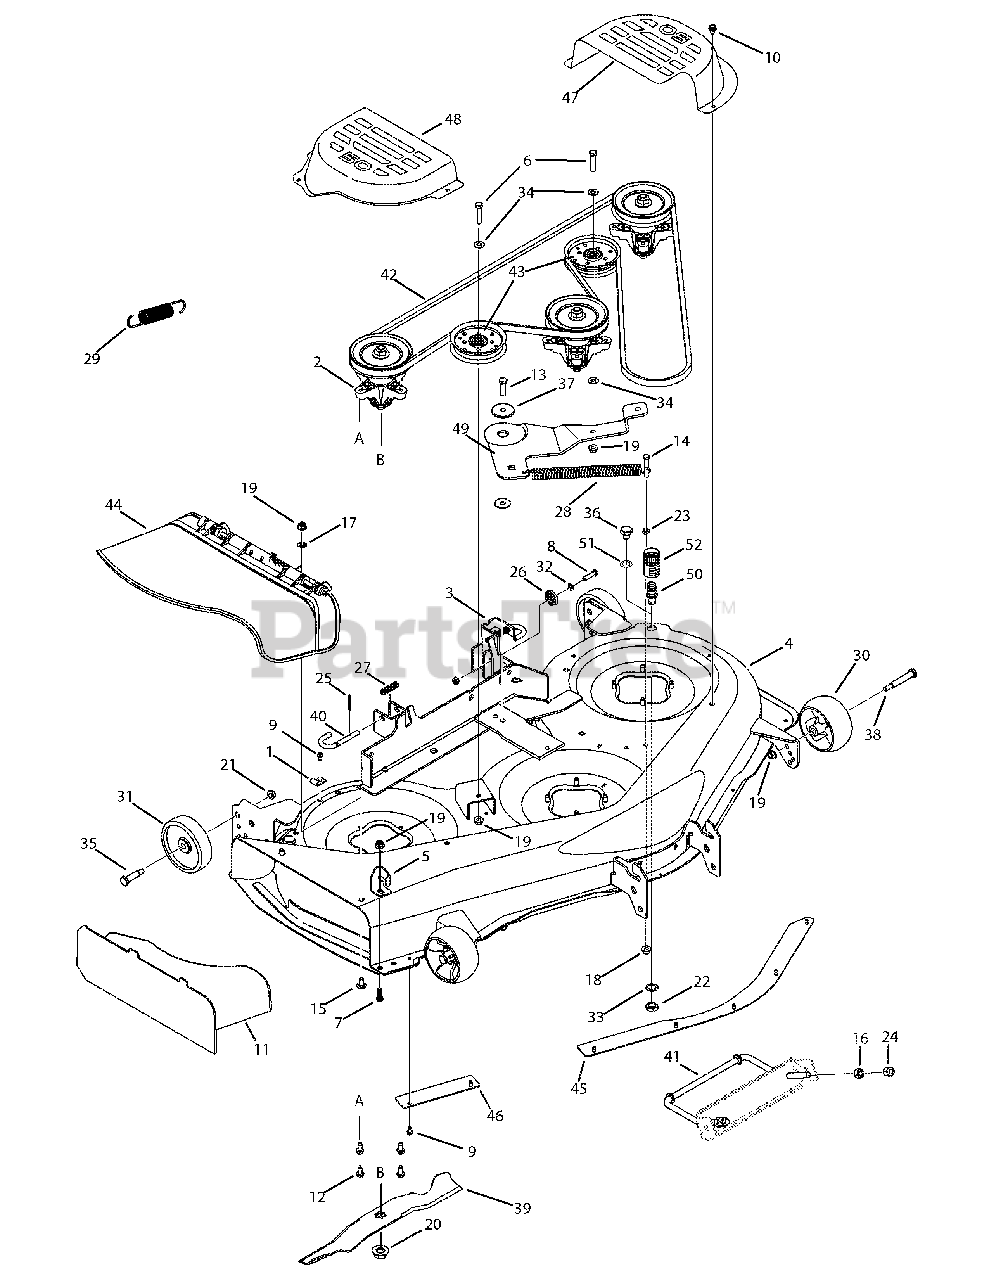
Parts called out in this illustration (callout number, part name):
1	Hook, Retainer
2	Spindle Assembly
6	Screw, 3/8-16, 1.75
7	Screw, 3/8-16 x 1.0
8	Screw, 5/16-18, 1.25, Gr5
9	Screw, 1/4-20 x 0.5
10	Screw, 5/16-18, .500
11	Mulch Plug
12	Screw, 5/16-18, .750
13	Screw, 3/8-16, 1.25
14	Screw, 5/16-18 x 2.00
15	Screw, Carriage, 3/8-16 x .75
16	Hex Nut, 1/2-13
17	Push Nut Retainer
18	Nut, Nylon Lock, 5/16-18
19	Nut, Nylon Lock, 3/8-16
20	Nut, Hex, Flange, 5/8-18
21	Nut, Nylon Lock, 3/8-16, Top Lock
22	Nut, Hex, M16-1.5
23	Nut, Hex, 5/16-18, Gr5
24	Hex Lock Nut, 1/2-13
25	Pin, Cotter, 1/8 x 1.25
26	Deck Adjustment Gear
27	Spring, Compression, .531 x 1.75
28	Spring, Extension, .94 x 6.74
29	Spring, Lift Assist
30	Deck Wheel, 5.0
31	Deck Wheel, 5.0
32	Washer, Lock, 5/16
33	Lock Washer, 5/8"
34	Washer, Flat, .406 x .875 x .059
35	Shoulder Screw
37	Spacer, Shoulder, .884 x .190
38	Shoulder Screw
39	Blade, 17.90
40	Rod, Deck Release .375 Dia.
41	Rod, Deck Adjust
42	Belt, V-Type
43	Pulley, Idler, 3.5"
44	Chute Assembly, Side Discharge
50	Port, Water
51	Flat Washer, .64 x 1.24 x .06
52	Water Nozzle Adapter
